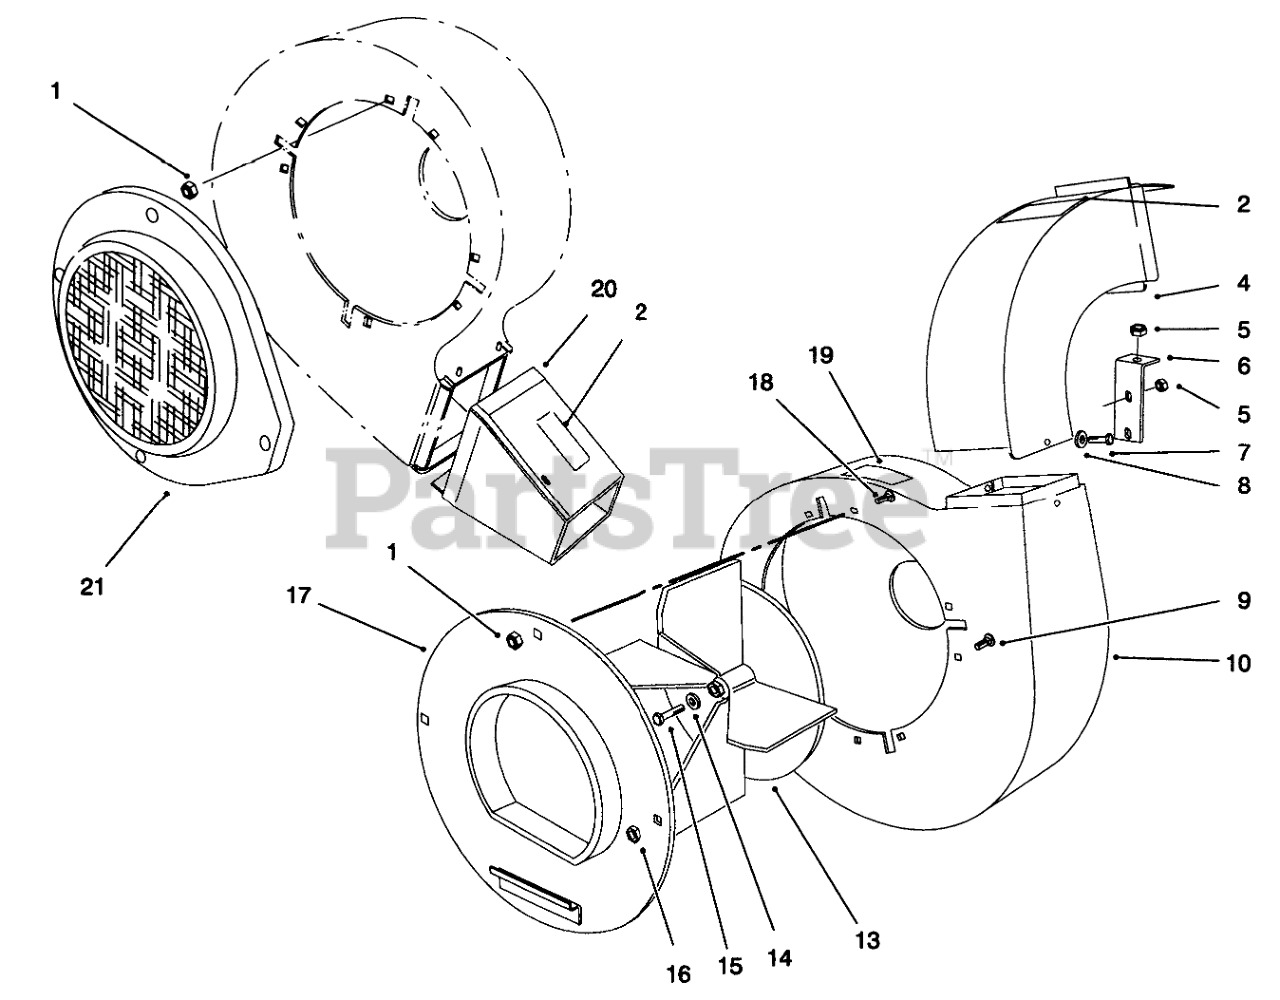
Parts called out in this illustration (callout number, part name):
1	NUT-FLANGE
2	DECAL-CAUTION, BAG
4	Chute-Vacuum
5	NUT-LOCK, NI
6	Bracket-Housing
7	SCREW-HH
8	WASHER-BELLEVILLE
9	SCREW-CARR
10	Blower Housing
13	Fan Assembly
14	WASHER-BELLEVILLE
15	SCREW-HH
16	NUT-LOCK, NI
17	Blower Cover
18	BOLT-CARR
19	Decal-Warning
20	Blower-Exhaust
21	INTAKE-BLOWER
